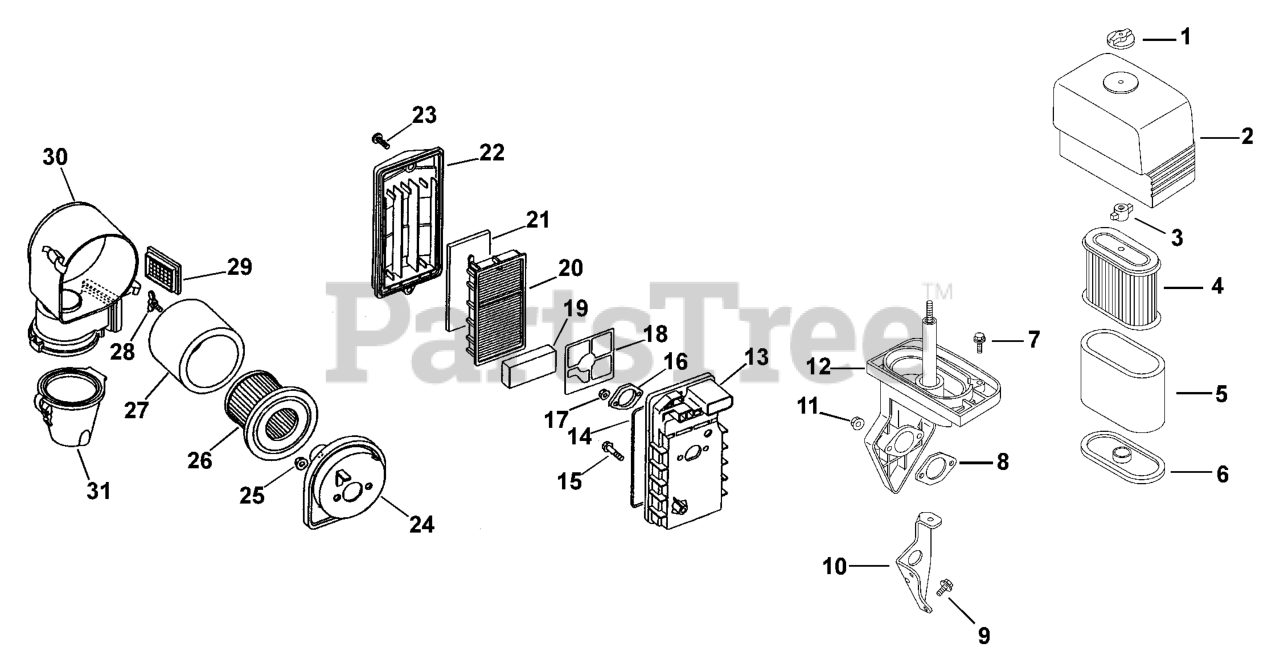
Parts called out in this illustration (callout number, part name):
1	NUT-(#DSC)
2	COVER, A/C
3	NUT, WING A/C
4	ELEMENT, A/C
5	PRE-CLEANER/ELEMENT
6	SEAL, A/C
8	GASKET, A/C 8.5
9	SCREW, HEX FLANGE
10	BRACKET, A/C CS8
12	BASE, A/C
